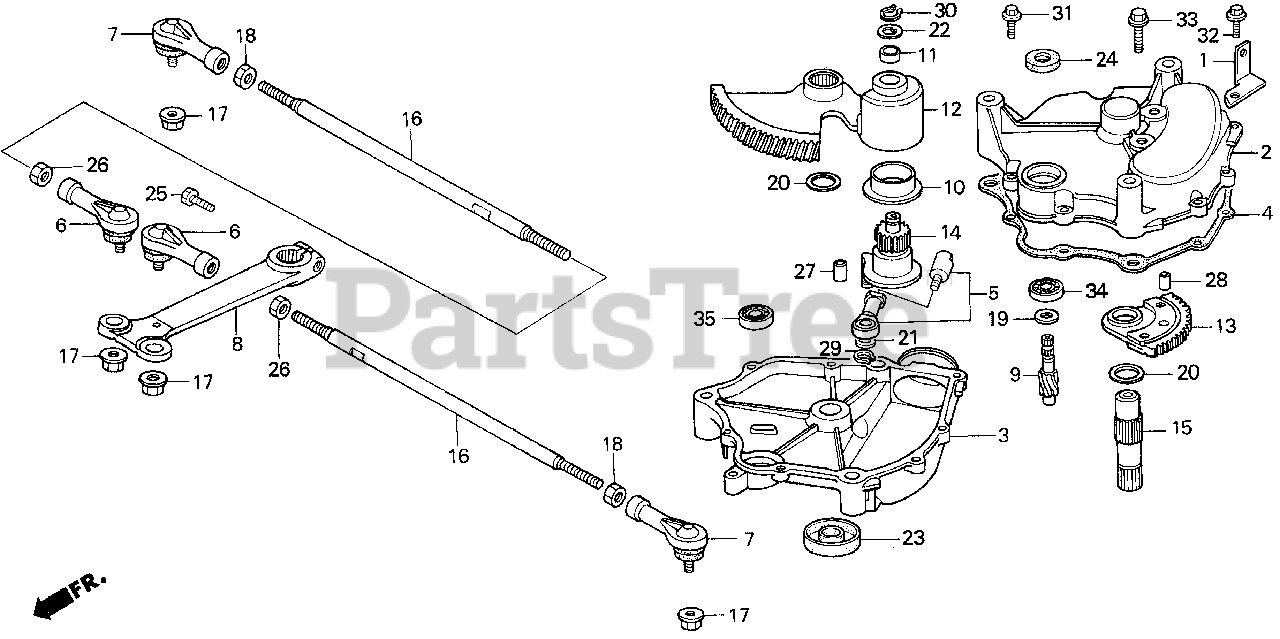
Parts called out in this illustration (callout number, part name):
1	BRACKET, HARNESS CLIP (A)
2	CASE, STEERING GEAR (UPPER)
3	CASE, STEERING GEAR (LOWER)
4	GASKET, STEERING CASE
5	JOINT, ROD END
6	JOINT, R. BALL (ER10)
7	JOINT, L. BALL (ER10)
8	ARM, PITMAN
9	PINION, STEERING
10	BUSH, PINION HOLDER (A)
11	BUSH, PINION HOLDER (B)
12	GEAR, STEERING
13	GEAR, SUN (67T)
14	GEAR, PLANETARY (19T)
15	SHAFT, STEERING SECTOR
16	TIE ROD, FR.
17	NUT, SELF-LOCK (10MM)
18	NUT, L. HEX. (10MM)
19	WASHER, THRUST (15MM)
20	WASHER, THRUST (25MM)
21	WASHER, THRUST (12MM)
22	WASHER (16.5X26X2)
23	OIL SEAL (25X38X7) (ARAI)
24	OIL SEAL (15X28X7)
25	BOLT, HEX. (10X40)
26	NUT, HEX. (10MM)
27	PIN, DOWEL (14X20)
28	PIN, DOWEL (10X16)
29	CIRCLIP, OUTER (12MM)
30	CIRCLIP (OUTER) (16MM)
31	BOLT, FLANGE (6X25)
32	BOLT, FLANGE (6X28)
33	BOLT, FLANGE (10X30)
34	BEARING, RADIAL BALL (6002UU)
35	BEARING, RADIAL BALL (6201)
